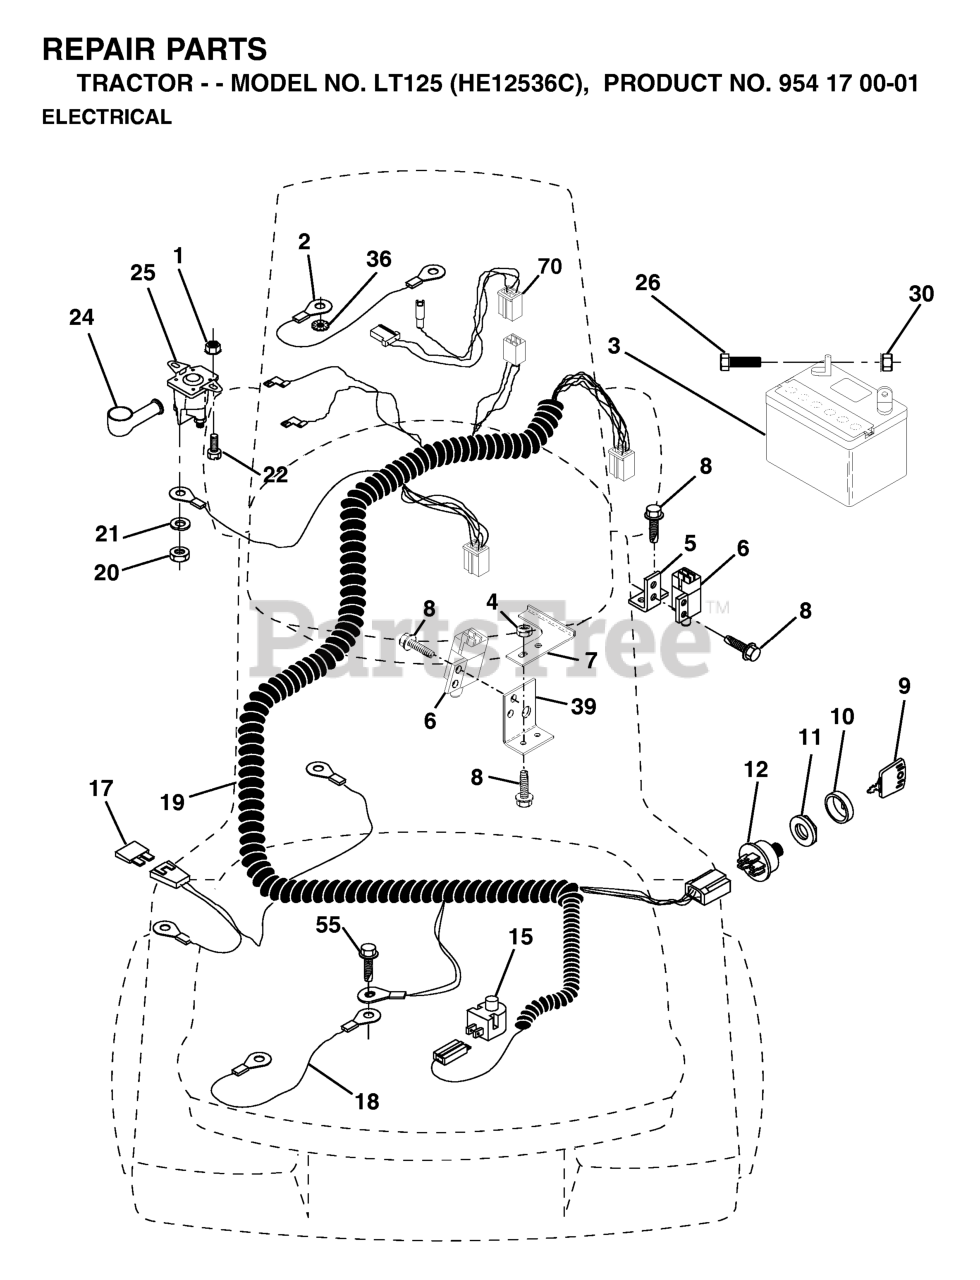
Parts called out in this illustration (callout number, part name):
1	Nut, Keps Blk Hex 1/4-20 UNC
2	CABLE.BATTERY.6GA.16"RED
3	REPL BY 532 12 38-99
5	BRACKET LT
6	SWITCH INTERLOCKT
7	KEEPER, ACTUAT. L.R.
9	KEY MLD GEN DELTA
10	COVER SWITCH KEY
11	NUT, IGNITION
12	IGNITION SWITCH
15	RP.SWITCH.PLUNGER.NC.GRAY
18	CABLE ASSY
19	HARNESS, IGN FEND
20	NUT
21	LOCKWASHER
22	BOLT
24	TERMINAL COVER
25	SOLINOID
26	BOLT.HEX.1/4.X.3/4.DICHROMATE
30	NUT
36	Washer, Lock, Internal Tooth 1/4
55	Screw 5/16-18 x 1/2 Hex, Self Tapping 5/16-18 x 1/2
70	HARNESS, ENGINE
